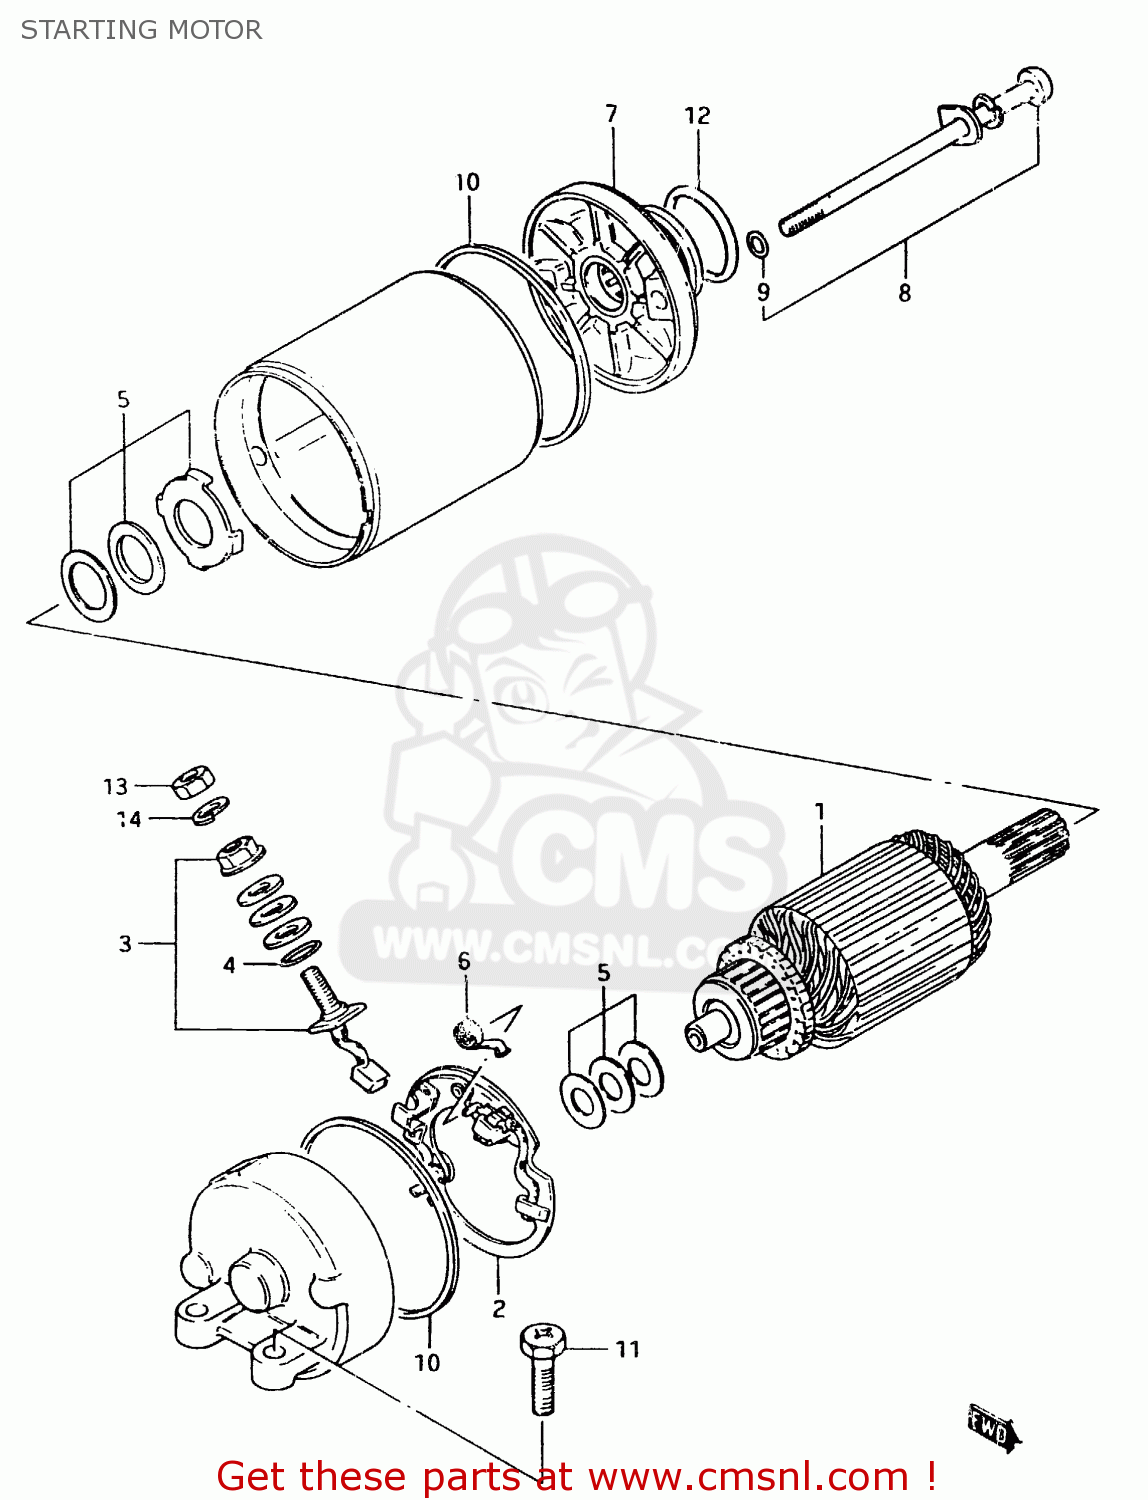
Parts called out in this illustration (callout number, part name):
1	ARMATURE
2	HOLDER SET,BRUSH(-)
3	TERMINAL SET,BRUSH,PLUS
4	O RING
5	SHIM SET,STARTING MOTOR
6	SPRING,BRUSH
7	BRACKET SET,STARTING MOTOR
8	BOLT SET,STARTING MOTOR
9	O RING
10	O RING
11	SCREW (6X25)
12	O RING(D:3,ID:24.5)
13	NUT
14	WASHER,LOCK
